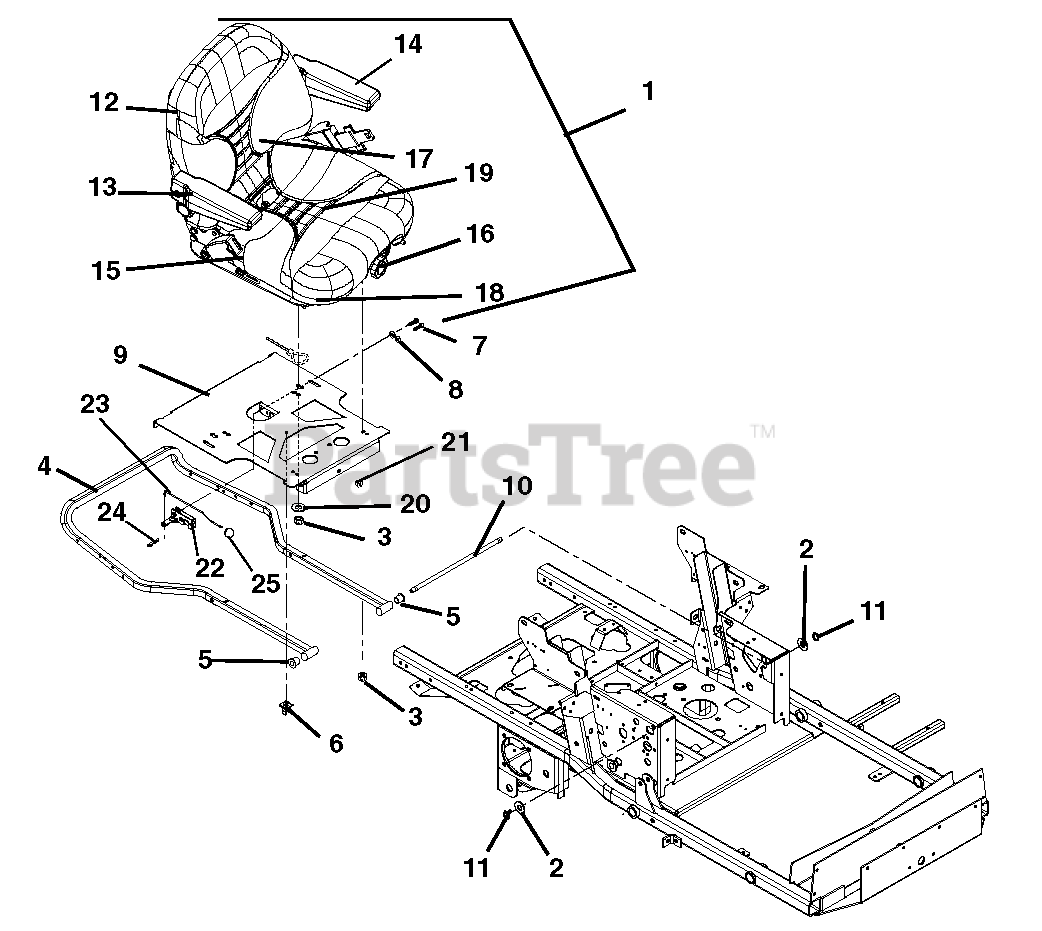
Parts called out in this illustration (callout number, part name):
1	Seat, Suspension -with Belt, Light Gray
2	Washer, Flat Steel .531 x 1.06 x .095
3	Nut, Locking-Top-Flange .31-18
4	Weldment, Hood Frame
5	Bushing, Flange .515 x .750 x .745 x 1.00
6	Clip, Routing
7	Bolt, Hex .25-20 x 1.00 Grade 5
8	Washer, Locking .25 x .062 Regular
9	Plate, Seat 200 XDZ with Latch
10	Rod, Seat Frame Pivot
11	Ring, Retaining-External .500 x .050
12	Kit, Back Cushion, Light Grey
13	Kit, Right Hand Armrest Assembly
14	Kit, Left Hand Armrest Assembly
15	Kit, Seat Cusion, Light Grey
16	Kit, Seat Knobs
17	Kit, Seat Back
18	Kit, Seat Slides
19	Kit, Seat Spring and Saddle
20	Washer, Flat Steel .344 x 1.25 x .135
21	Bushing, POLYLINER-.38 SNAPIN
22	Latch, Rotary-Push To Close
23	Rod, Seat Latch Release
24	Pin, Hair Internal .06 x .25 x 1.12
